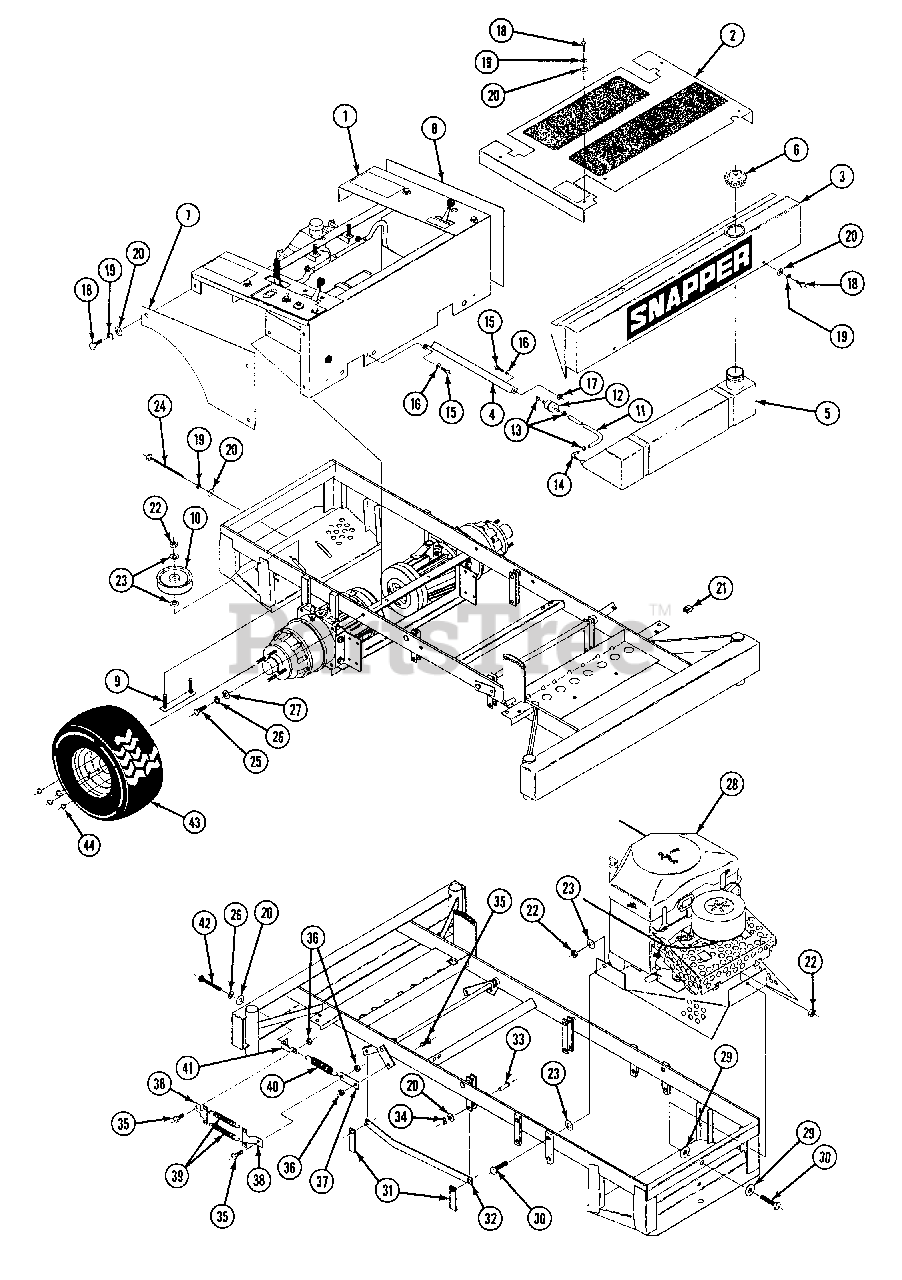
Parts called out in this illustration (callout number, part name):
1	SEAT SUPPORT ASSEMBLY
2	FOOT DECK ASS'Y: 1810, 2010 (ORANGE)
3	TANK COVER ASS'Y: 1810, 2010 (ORANGE)
4	GAS CHANNEL: FOR 1810, 2010
5	FUEL TANK
6	FUEL TANK CAP
7	FENDER SKIRT ASSEMBLY, RH: FOR 1810
8	FENDER SKIRT ASSEMBLY, LH: FOR 1810
9	IDLER SLIDE WELDMENT
10	V-IDLER, 4-3/8 O.D.
11	FUEL LINE
12	FUEL FILTER
13	CLAMP, HOSE: 1/4 HH SCREW 1/4 MIN.
14	HOSE BARB, 90 DEG 1/4 HOSE X 1/8 NPTM
15	CAPSCREW, HX HD: 1/4-20 X 3/4
16	FLAT WASHER: 1/4
17	LOCKNUT, NYLOCK: 1/4-20
18	CAPSCREW, HX HD: 5/16-18 X 3/4 GR5
19	LOCKWASHER, SPLT SPRNG: 5/16
20	FLAT WASHER, 5/16
21	J-NUT, 5/16-18 X 1 TINNERMAN
22	LOCKNUT, STOVER: 1/2-13
23	FLAT WASHER: 1/2
24	CAPSCREW, HX HD: 5/16-18 X 6 GR5
25	CAPSCREW, HX HD: 3/8-16 X 1
26	LOCKWASHER, SPLIT SPRING: 3/8
27	FLAT WASHER: 3/8
28	ENGINE ASSEMBLY
29	WASHER, 1/2 ID X 2 OD X 3/16
30	CAPSCREW, HX HD: 1/2-13 X 2
31	DECK HANGER BAR: FOR 1810, 2010
32	CONNECTING BAR: FOR 1810, 2010
33	CLEVIS PIN: FOR 1810, 2010 5/16 X 1-1/4
34	RUE RING, 5/16-3/8
35	CAPSCREW, HEX HEAD: 3/8-16 X 1
36	LOCKNUT, NYLOCK: 3/8-16
37	PLATE, SPRING: FOR 1810, 2010
38	PLATE, DOUBLE SPRING (IF USED)
39	SPRING, EXTENSION (IF USED)
40	SPRING, EXTENSION
41	TIGHTNER, SPRING
42	CAPSCREW, HX HD: 3/8-16 X 5 FULL THD
43	WHEEL / TIRE ASS'Y (20-8-10 4 PLY)
44	LUG NUT: 1/2-20 X 60 DEGREE
